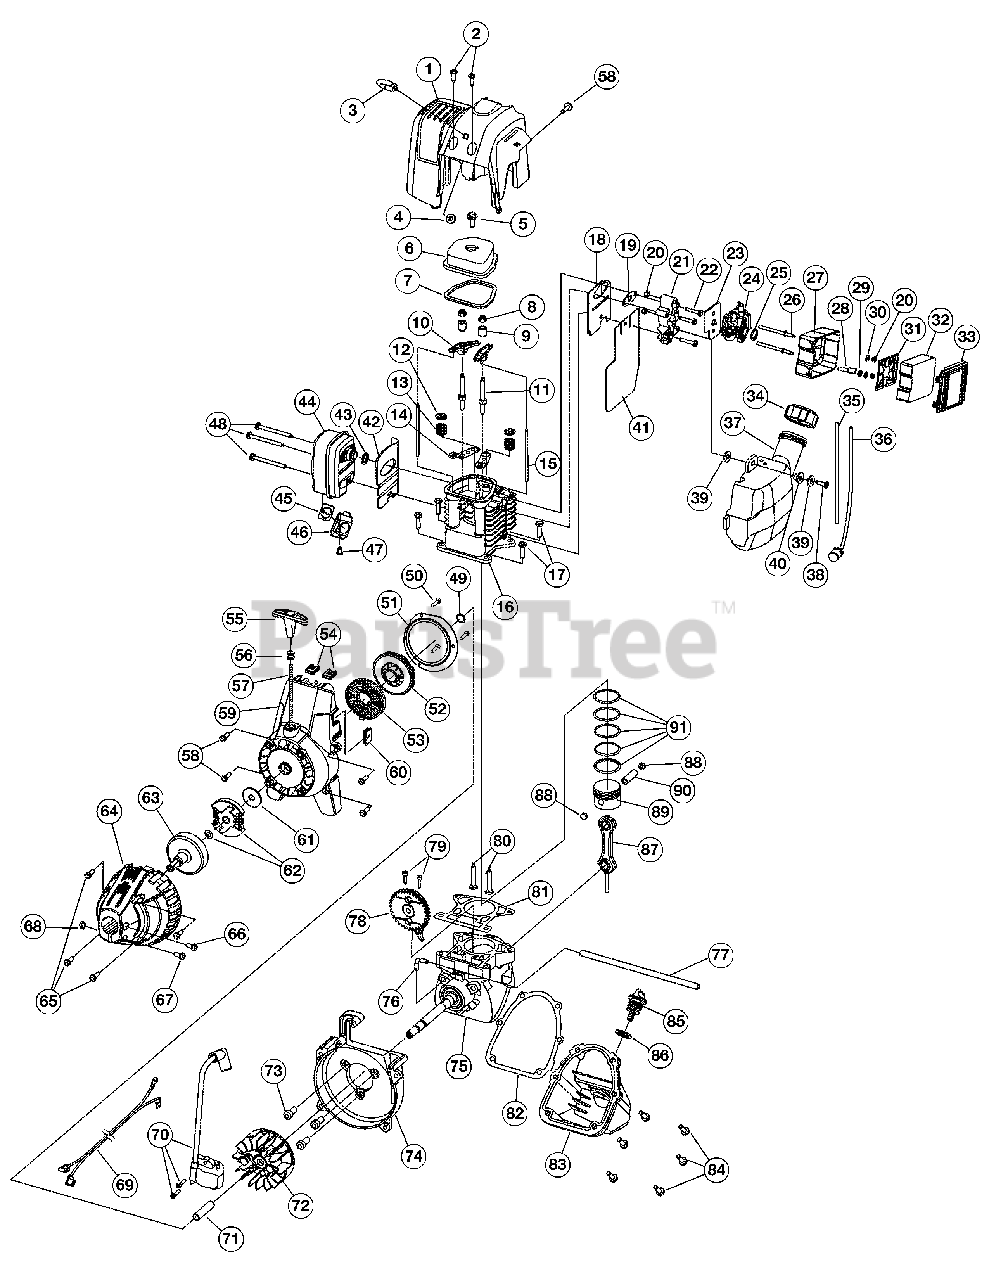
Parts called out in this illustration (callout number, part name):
1	Engine Cover Assembly (includes 3 & 4)
2	Engine Cover Screw
3	Starter Rope Eyelet
4	Eyelet Nut
5	Valve Cover Screw
6	Valve Cover
7	Valve Cover Gasket
8	Rocker Adjustment Nut
9	Rocker Arm Pivot
10	Rocker Arm
11	Rocker Arm Stud
12	Valve Spring Retainer
13	Valve Spring
14	Push Rod Guide
15	Push Rod
16	Cylinder Assembly (Includes 11-14, 17, 80 & 81)
17	Cylinder Screw
18	Intake Baffle
19	Carburetor Mount Gasket
21	Carburetor Mount (includes 20)
22	Carburetor Mount Screw
23	Carburetor Gasket
24	Carburetor with Primer
25	Air Filter O-Gasket
26	Air Filter Mounting Screw
27	Air Filter Cover Assembly (Includes 28, 29, 31-33)
28	Breather Tube Assembly
29	Grommet Washer
31	Air Filter Plate
32	Air Filter
33	Air Filter Cover
34	Fuel Cap
35	Fuel Return Line
36	Fuel Pick-Up Line with Filter
37	Fuel Tank Assembly (includes 34-36)
40	Bushing
41	Fuel Tank Shield
42	Muffler Baffle
43	Muffler Gasket
44	Muffler (includes 43, 45-47)
45	Spark Arrestor Screen
46	Screen Cover
48	Muffler Mounting Screw
49	Palnut
50	Plate Screw
51	Pressure Plate Assembly (includes 50)
52	Recoil Pulley Assembly (includes 49 & 57)
53	Recoil Spring
54	Nut Clip
55	Pull Handle
56	Rope Guide
58	Housing Screw
59	Starter Housing Assembly (includes 49-58)
60	Wire Grommet
61	Clutch Washer
62	Clutch with Washer
63	Clutch Drum
64	Clutch Cover Assembly (includes 65-68)
65	Clutch Cover Screw
66	Anti-Rotation Screw
67	Screw
68	Nut
69	Lead Wire
70	Ignition Module with Screws
71	Spacer
72	Flywheel
74	Shroud Assembly (includes 73)
75	Crankcase Assembly (includes 76 & 77)
76	90° Elbow
77	Breather Hose
78	Cam Bracket Assembly
79	Cam Bracket Screw
80	Valves, Intake and Exhaust
81	Cylinder Gasket
82	Oil Pan Gasket
83	Oil Pan (includes 82 & 84)
84	Oil Pan Screw
85	Dipstick Assembly (includes 86)
87	Connecting Rod
88	Wrist Pin Button
89	Piston (includes 91)
90	Wrist Pin
91	Piston Ring Set
